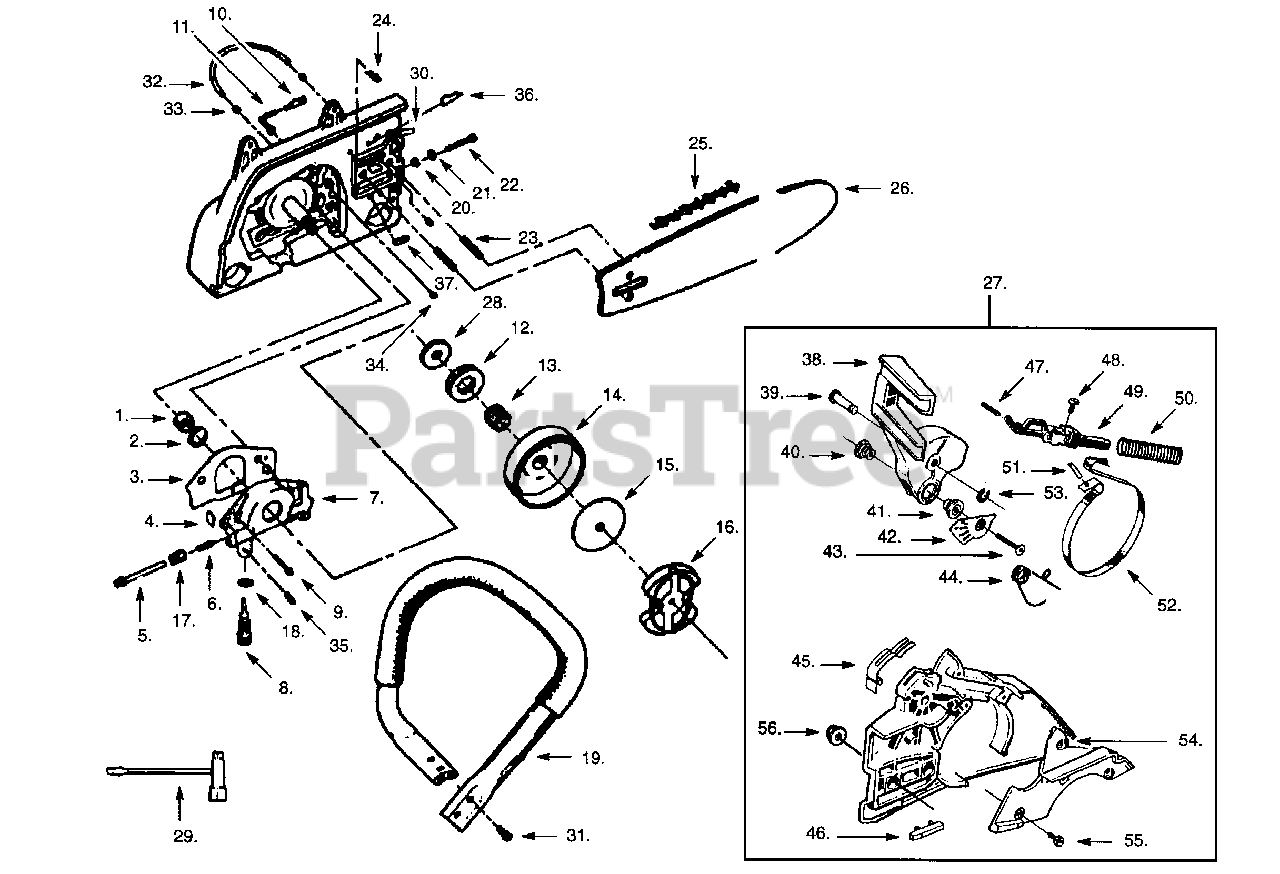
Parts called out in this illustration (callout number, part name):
1	Worm Gear
3	Model 336C
3	Model 365C
4	Dust Plug
7	Oil Pump Kit (Incl.1,2,4-6,8,17,18,35)
9	Screw
10	Oil Pickup & Filter
11	Oiler Intake Line
12	Rim Sprocket
14	Drum Sprocket
15	Clutch Plate
16	Clutch Ass'y.
17	Oiler Gear Spur
18	"O" Ring
19	Handlebar
20	Bar Adjusting Pin
21	"E" Ring
22	Screw
23	Bar Stud
24	Vent Pin
27	Chainbrake Ass'y.
30	Crankcase Plug
32	Oiler Discharge Line
33	Oiler Discharge Sleeve
34	Tubing Nut
35	Oiler Adjustment Pin
36	Chain Pad-Top
37	Chain Pad
38	Handguard Ass'y.
39	Pivot Pin
40	Right Bushing
41	Left Bushing
42	Heat Shield
44	Handguard Spring
45	Detent Spring
46	Chain Pad
47	Straight Pin
48	Screw
49	Knee Joint Ass'y.
50	Chain Brake Spring
51	Spiral Pin
52	Brake Band
53	"C" Clip
54	Spring Cover
55	Screw
56	Nut
